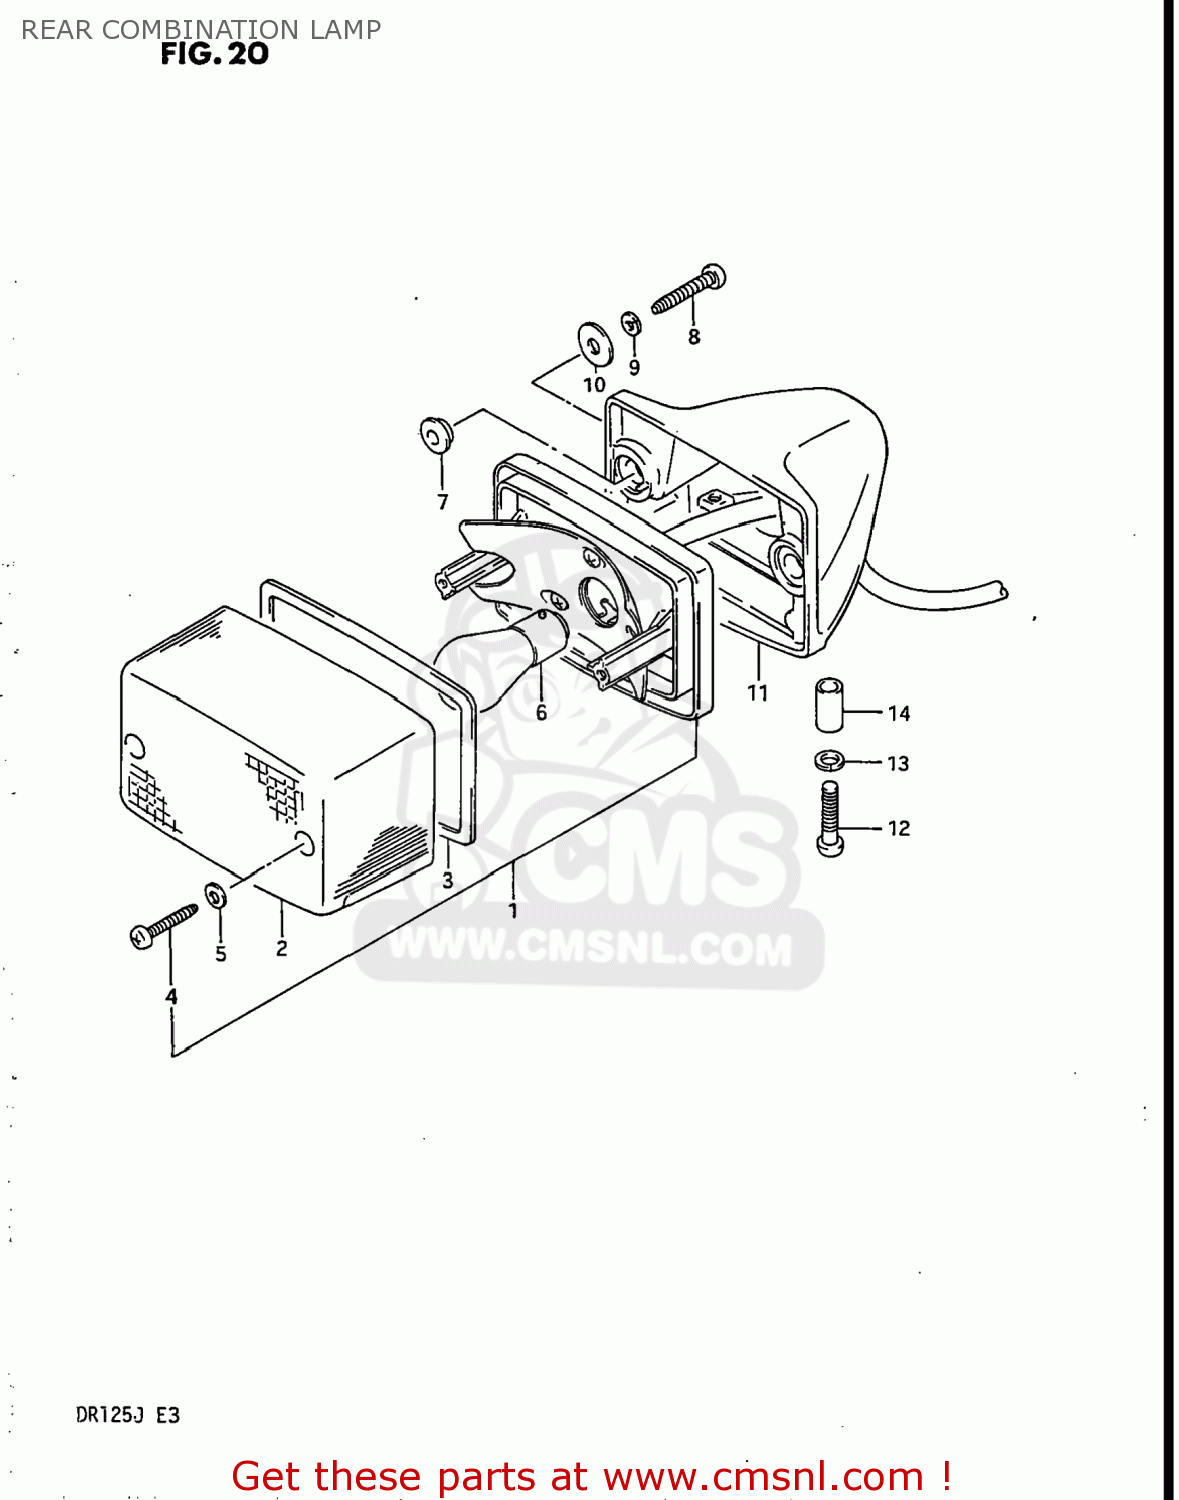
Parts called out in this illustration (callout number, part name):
1	LAMP UNIT,REAR COMBINATION
2	LENS,REAR COMBINATION LAMP
3	GASKET,RR COMBI LAMP LENS (NAS)
4	SCREW
5	GASKET (NAS)
6	BULB(6V5W,TOKAI DENSO)
7	SPACER,RR COMBI
8	SCREW
9	WASHER,LOCK
10	WASHER
11	BRACKET UNIT,TAIL LAMP
12	SCREW
13	WASHER,LOCK
14	SPACER(6.4X9.2X12)
